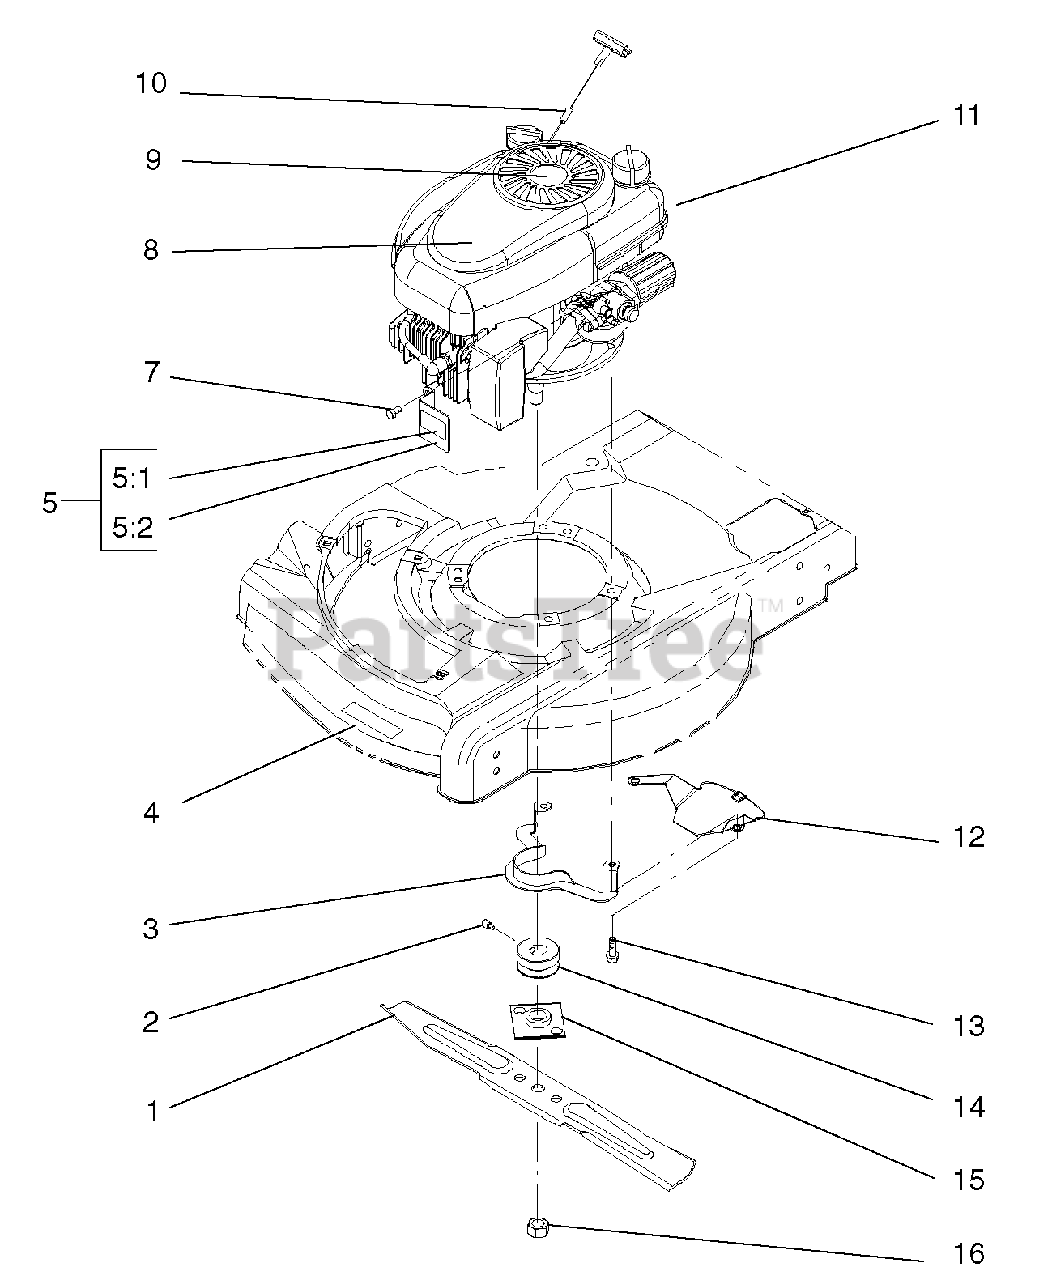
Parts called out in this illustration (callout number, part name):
2	Screw-Set
3	Guide-Belt
4	Decal-Deck
5	Muffler Guard ASM (only on: 10360)
5	Muffler Guard ASM (only on: 10360c)
5:1	Decal-Surface, Hot (only on: 10360)
5:1	Decal-Surface, Hot (only on: 10360c)
5:2	Guard-Muffler
8	Applique
9	Decal-Recoil,5hp
10	Stop-Rope
11	Engine LEV120-361545B
12	Shield-Grass
13	Screw-Taptite W/Patch
15	Blade Retainer ASM
16	Nut-Blade
